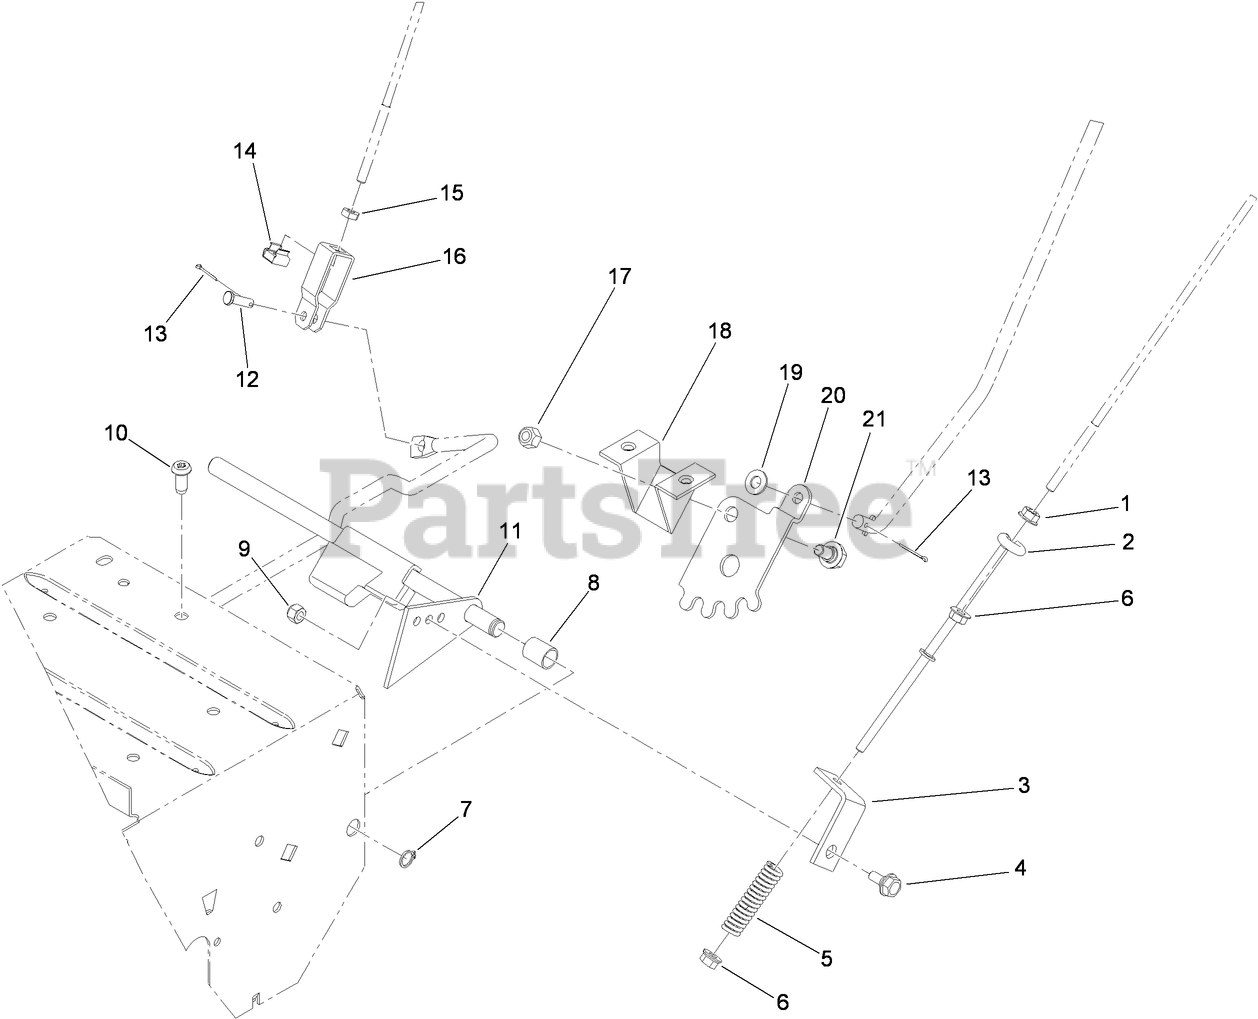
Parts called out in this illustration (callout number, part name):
1	NUT-HF
2	ROD-TRACTION, LOWER
3	BRACKET-TRACTION
4	SCREW
5	SPRING
6	NUT-HHF
7	RING-RETAINING
8	SPACER
9	NUT-LOCK, NI
10	SCREW-BHTF
11	TRACTION ARM ASM
12	PIN-CLEVIS
13	PIN-COTTER
14	NUT-RETAINED
15	NUT-JAM
16	CLEVIS
17	NUT-LOCK, NI
18	MOUNT-LEVER
19	WASHER-PLAIN
20	GEAR-QUADRANT
21	BOLT-SHOULDER
